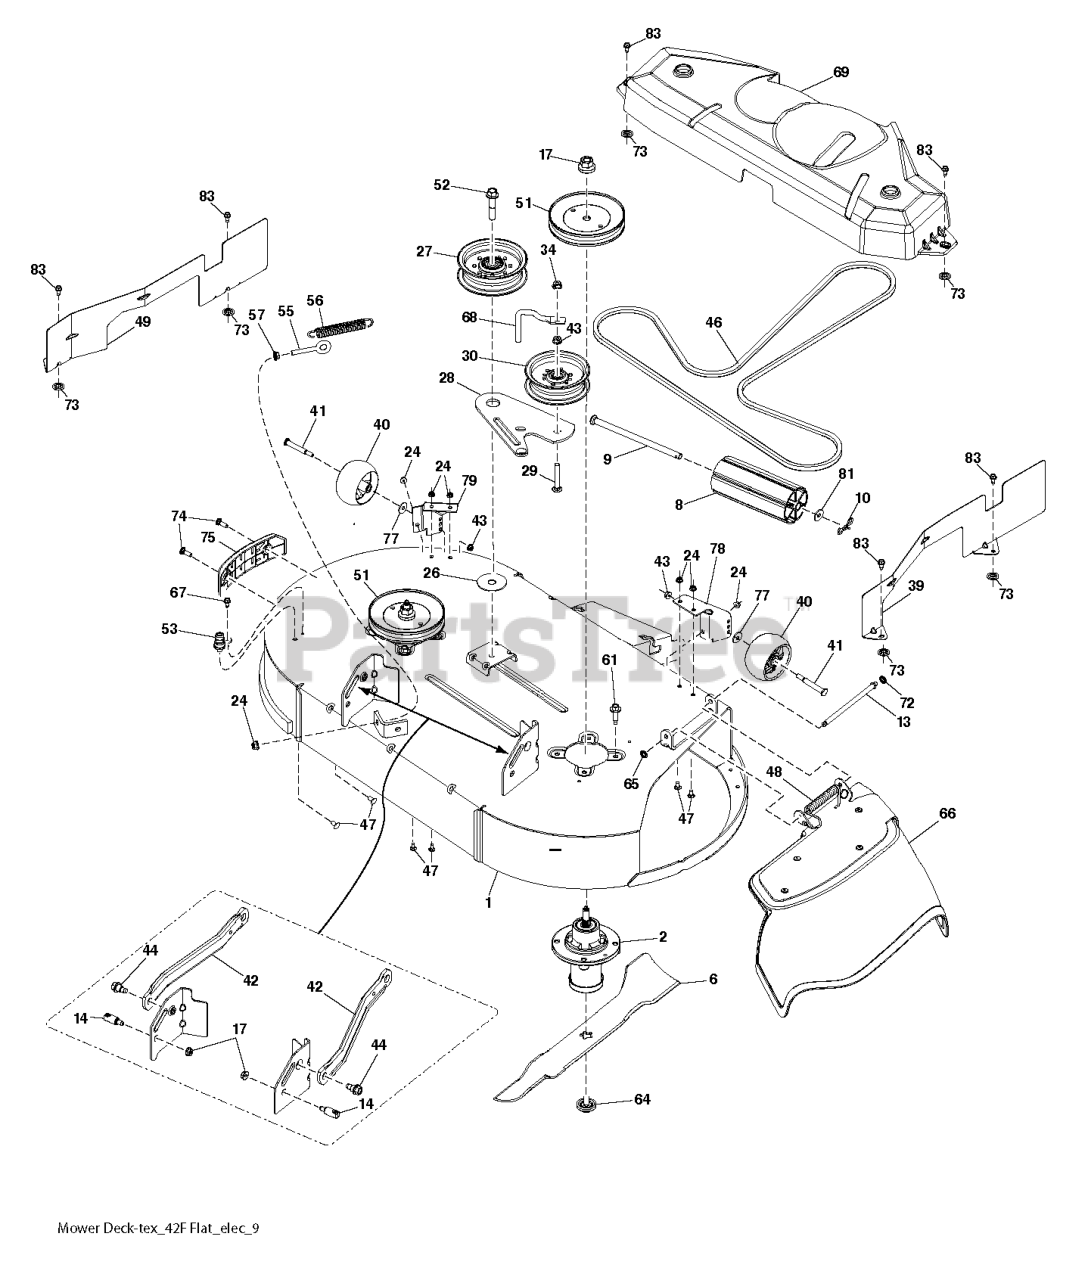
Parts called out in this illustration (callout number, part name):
2	MANDREL ASM, CAST IRON
6	BLADE 42 CLEARCUT EURO NON-REV
8	NOSE ROLLER 48"
9	ROD.ROLLER.NOSE.NARROW.48"
10	PIN.COTTER.5/16.BOW TI
13	ROD.HINGE
14	STUD.FASTNER.W/ANTI-ROTATE
17	NUT LOCK HEX FLANGE 5/16-18
24	5/16-18 NYLOC FLANGE NUT
27	PULLEY.IDLER.MWR.STATI.LH
28	ARM.42"FCS.CLUTCHING.X431
29	CARRIAGE BOLT 3/8-16 X
30	PULLEY.IDLER.2006
39	SHIELD.42.CLEARCUT.RH.DECK.431
40	WHEEL.GAUGE.RALLY
41	BOLT.SHOULDER.3/8-16X3-5/8.
42	ARM.SUSPENSION.MOWER
43	NUT LOCK FLG 3/8-16 UNC
44	BOLT.SHOULDER
46	BELT.42.CLEARCUT.DECKDRIVE.EUR
47	BOLT 5/16C X 3/4" CARRIAGE
48	SPRING.42.FCS.DEFLECTOR
49	SHIELD.42CLRCUT.LH.DECK.SD.431
51	PULLEY.MANDREL.5.438.PD
52	SCREW.7/16-14 X 2.125.WASHER
53	PORT.WASHOUT
55	EYE BOLT 5/16 X 3.50
56	SPRING.EXTN.42.FCS.TR.DECK.DRV
57	NUT 5/16C WHIZ
61	BOLT.HEX.WASHR.HED.313-18X1.19
64	BOLT.WASHER.ASM.7/16-2
65	NUT PUSH M
66	DEFLECTOR.ASM.42.FCS.ORANGE
67	SCREW.1/4-20X5/8
68	KEEPER.BELT.IDLER.54"T
69	COVER.42.CLRCUT.EU.MANDREL.498
72	CAP-SLEEVE LT
73	PALNUT 1/4
74	SHOULDER BOLT 5/16-18TT
75	BUMPER.42CC.TRIM.SIDE.ASSY.HUS
77	WASHER.5/16.FLAT.STE.STD.
78	BRACKET.PNT.GA-WHEEL.FCS.42.RH
79	BRACKET.PNT.GA-WHEEL.42FCS.LH
81	BUSHING.NOSE.ROLLER
83	SCR 1/4-20X5/8 HEX SELF TAP ZD
